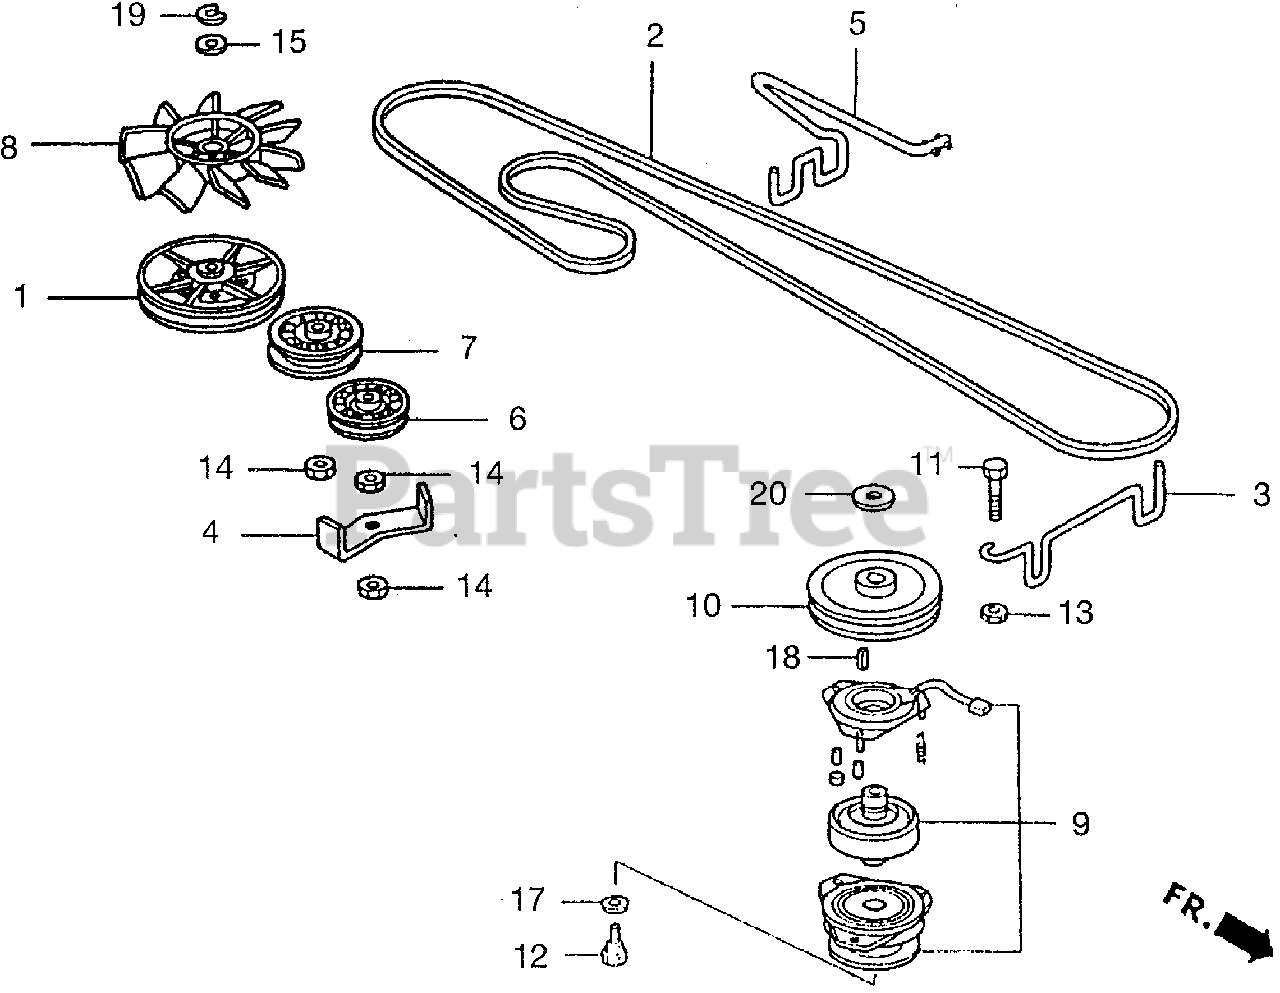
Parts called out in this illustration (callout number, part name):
1	PULLEY, DRIVEN
2	V-BELT, TRANSMISSION
3	STOPPER A, BELT
4	STOPPER B, BELT
5	STOPPER C, BELT
6	ROLLER A, TENSIONER
7	ROLLER B, TENSIONER
8	FAN, TRANSMISSION COOLING
9	CLUTCH ASSY., FR.
10	PULLEY, ENGINE
11	BOLT, CARRIAGE (8X20)
12	BOLT, P.T.O.
13	NUT, FLANGE (8MM)
14	NUT, FLANGE (10MM)
15	WASHER, FAN BLADE
17	WASHER, P.T.O.
18	KEY (6.3X6.3X43)
19	RING, FAN SNAP
20	WASHER, FLAT DRIVE
